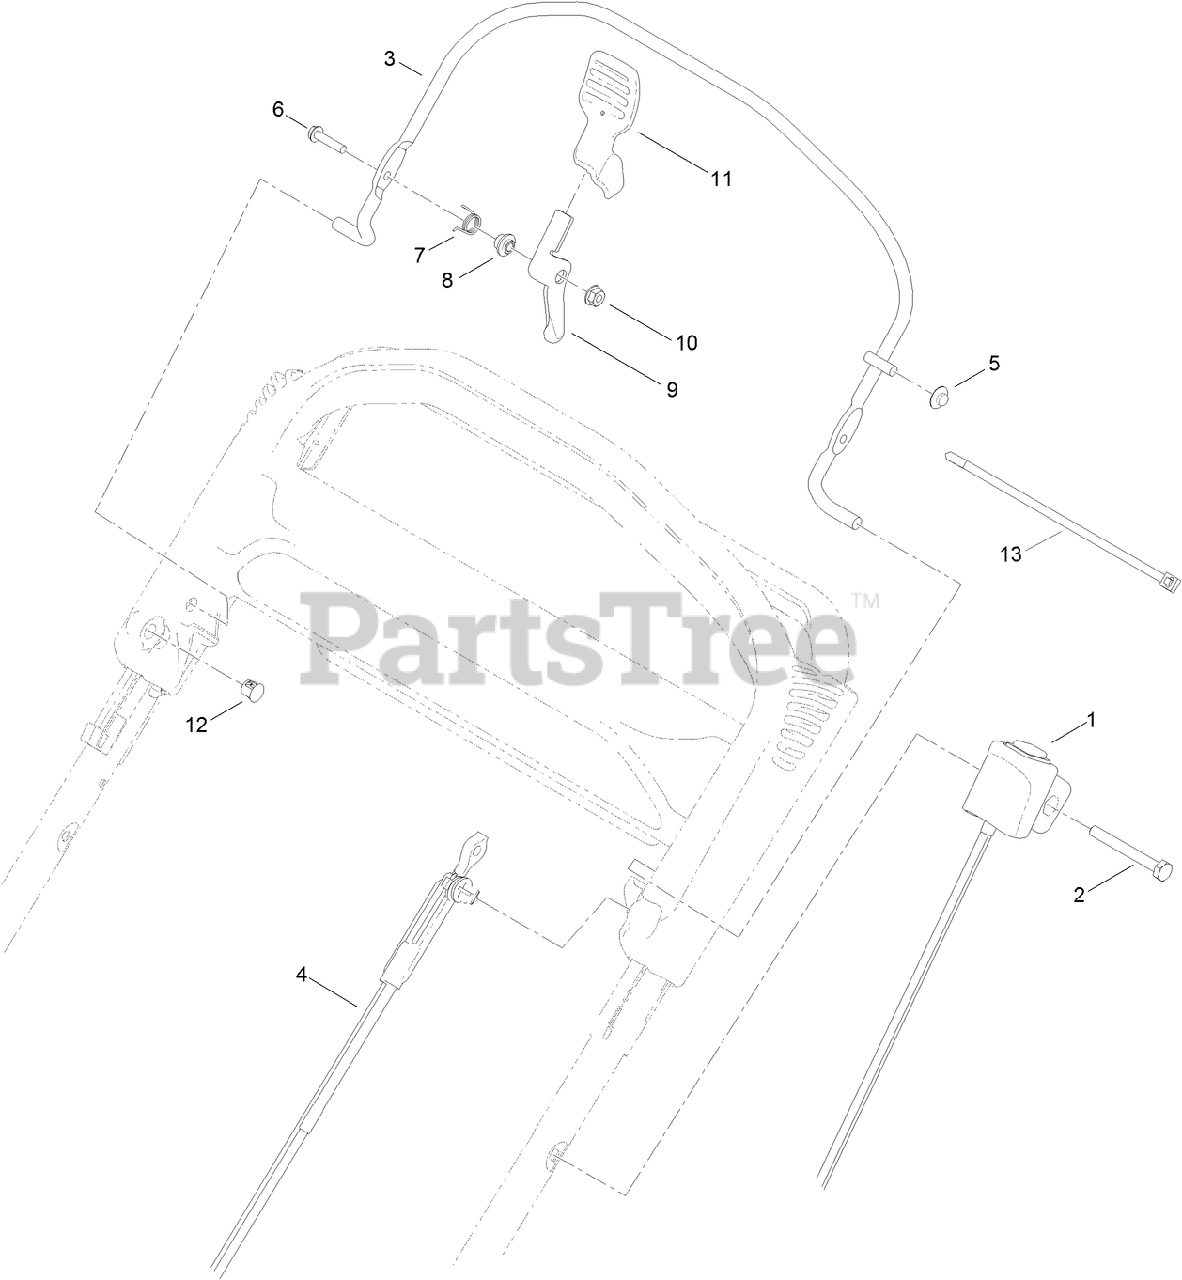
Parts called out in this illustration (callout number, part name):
1	SWITCH HOUSING ASM
2	SCREW-HH
3	BAIL-BRAKE
4	CABLE-BRAKE
5	NUT-SPEED
6	SCREW-HWH
7	SPRING-TORSION
8	SPACER
9	LEVER
10	NUT-LOCK, FLANGE
12	PLUG-DOME
13	TIE-CABLE
